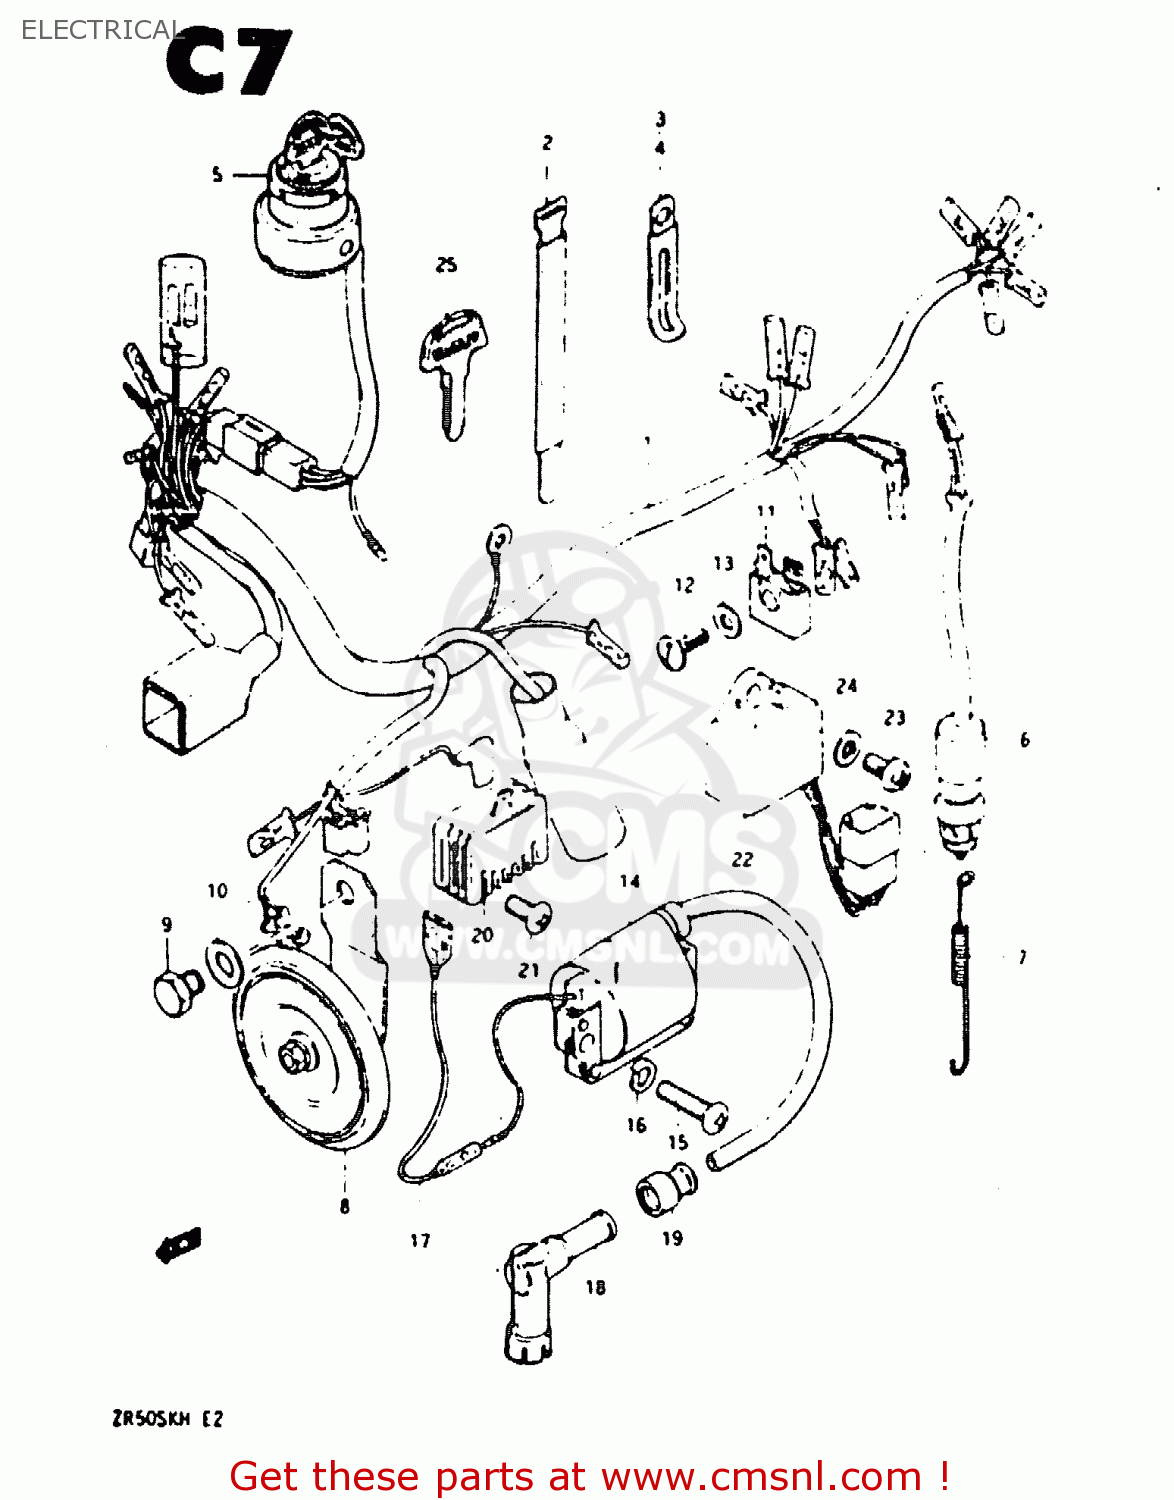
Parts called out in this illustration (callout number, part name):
1	WIRING HARNESS
2	CLAMP
3	CLAMP
4	CLAMP
5	SW ASSY IGNITIO
6	SWITCH ASSY,STOP LAMP
7	SPRING
8	HORN
9	BOLT,8X16
10	WASHER
11	RECTIFIER ASSEMBLY
12	SCREW(5X18)
13	WASHER
14	COIL, IGNITION
15	SCREW
16	WASHER,LOCK
17	LEAD WIRE, IGNITION COIL
18	CAP,SPARK PLUG
19	SEAL,SPARK PLU
20	REGULATOR ASSY,VOLTAGE
21	SCREW 6X12
22	CDI UNIT
23	SCREW 6X12
24	WASHER
25	KEY,BLANK
